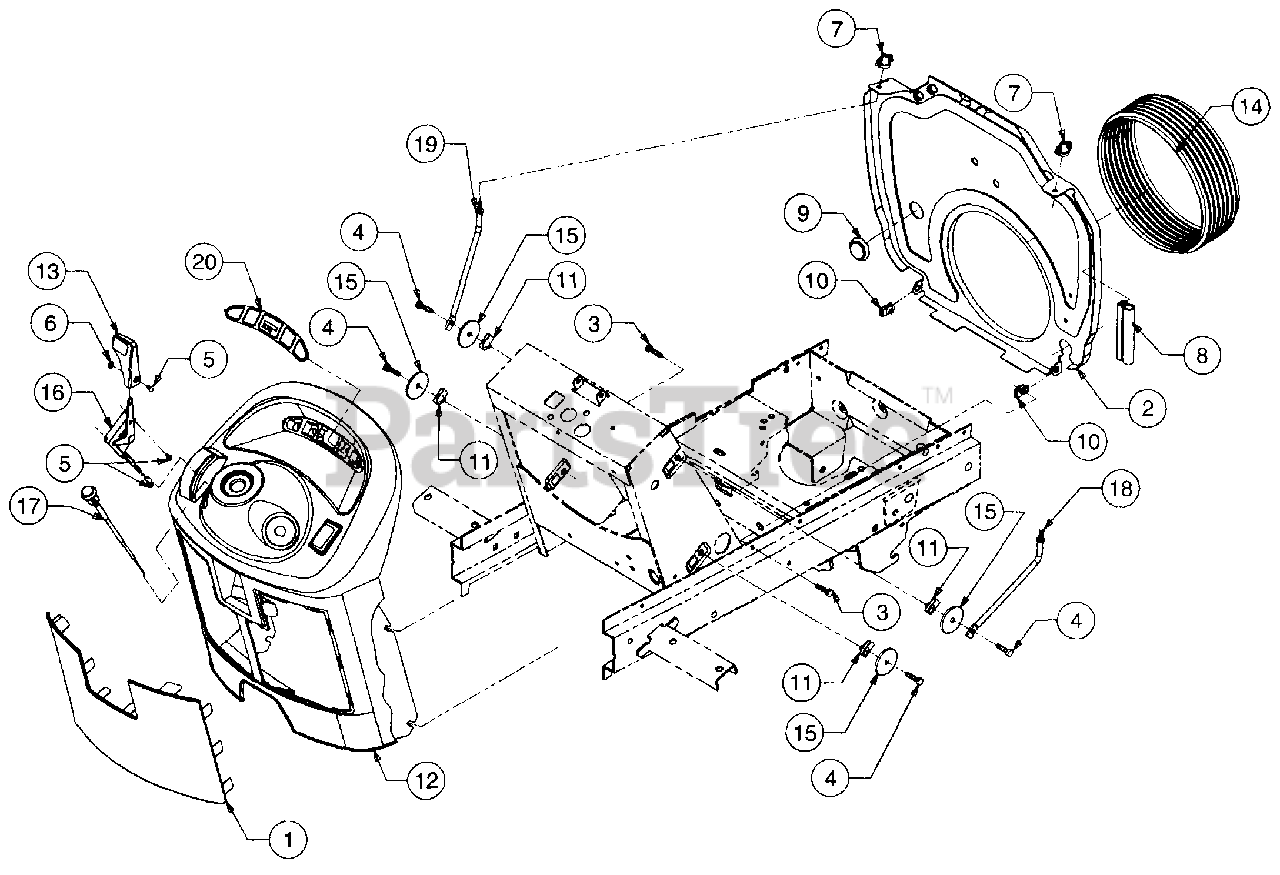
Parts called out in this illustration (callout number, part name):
2	Bulkhead, Lower
3	Screw, Hex Cap, 1/4-20 x .625
4	Screw, Hex Cap, 1/4-20 x 1.0
5	Screw, Cross Rec Truss Hd, #8-32 x .38
6	Nut, #8-32
7	Nut, Wing w/Bell Washer 1/4-20
8	Seal, Push-on Trim, 1/4
9	Plug, Button, 1.12 Dia
10	Nut, U-Type Speed, 1/4-20
11	Nut, U-Clip, 1/4-20
12	Panel, Dash
13	Knob, Throttle
14	Boot, Intake
15	Washer, Flat, .285 x 1.75 x .10
16	Control, Throttle
17	Control, Choke
18	Rod, RH Mounting
19	Rod, LH Mounting
20	Label, Dash
